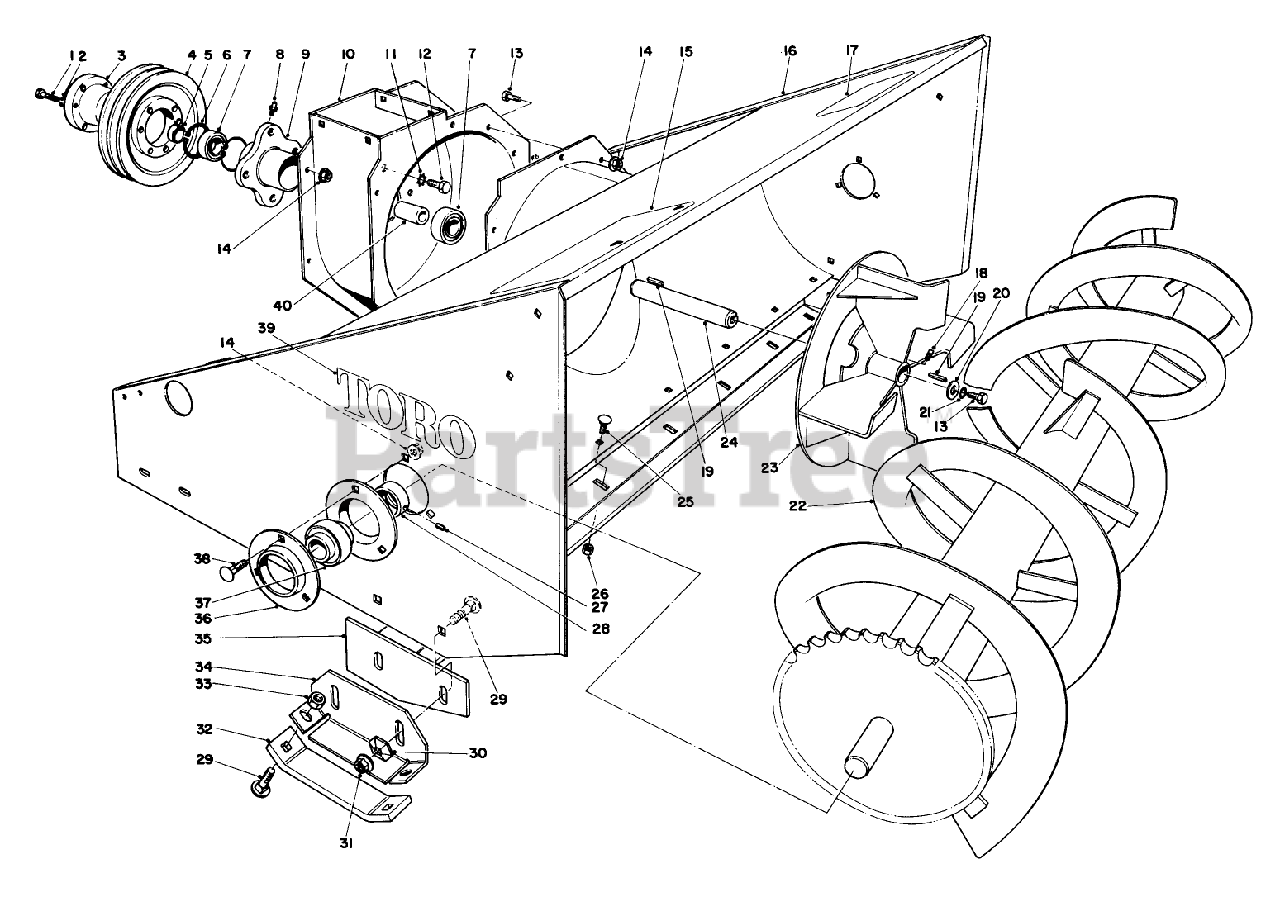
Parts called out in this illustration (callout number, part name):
1	SCREW-HH
2	WASHER-LOCK
3	Hub-"QD" (Incl. Ref. #1 & 2)
4	Pulley-"QD"
5	SPACER
6	RETAINING RING
7	BEARING
8	FITTING-LUBE, 45 DEG
9	SPINDLE HOUSING
10	BLOWER HSG WA
11	WASHER-LOCK, EXT
12	SCREW-HH
13	SCREW-HH
14	NUT-HF
15	Decal-Rear Weight
16	Auger Housing
17	Decal-Warning
18	SCREW-SET
19	Square Key
20	WASHER
21	WASHER-LOCK
22	Auger
23	IMPELLER WA 60096
24	IMPELLER SHAFT
25	SCREW-CARR
26	NUT-LOCK, NI
27	SCREW-SET, HSH
28	COLLAR-LOCK, BEARING
29	BOLT-CARR
30	LOCKWASHER-PYRAMID
31	FLANGE NUT W/LG FLG
32	SKID SHOE R
33	NUT-LOCK, CONE
34	SKID MTG PLT
35	SCRAPER WA
36	FLANGE
37	Bearing (Incl. Ref. #27 & 28)
38	SCREW-CARR
39	DECAL
40	SLEEVE 16107
